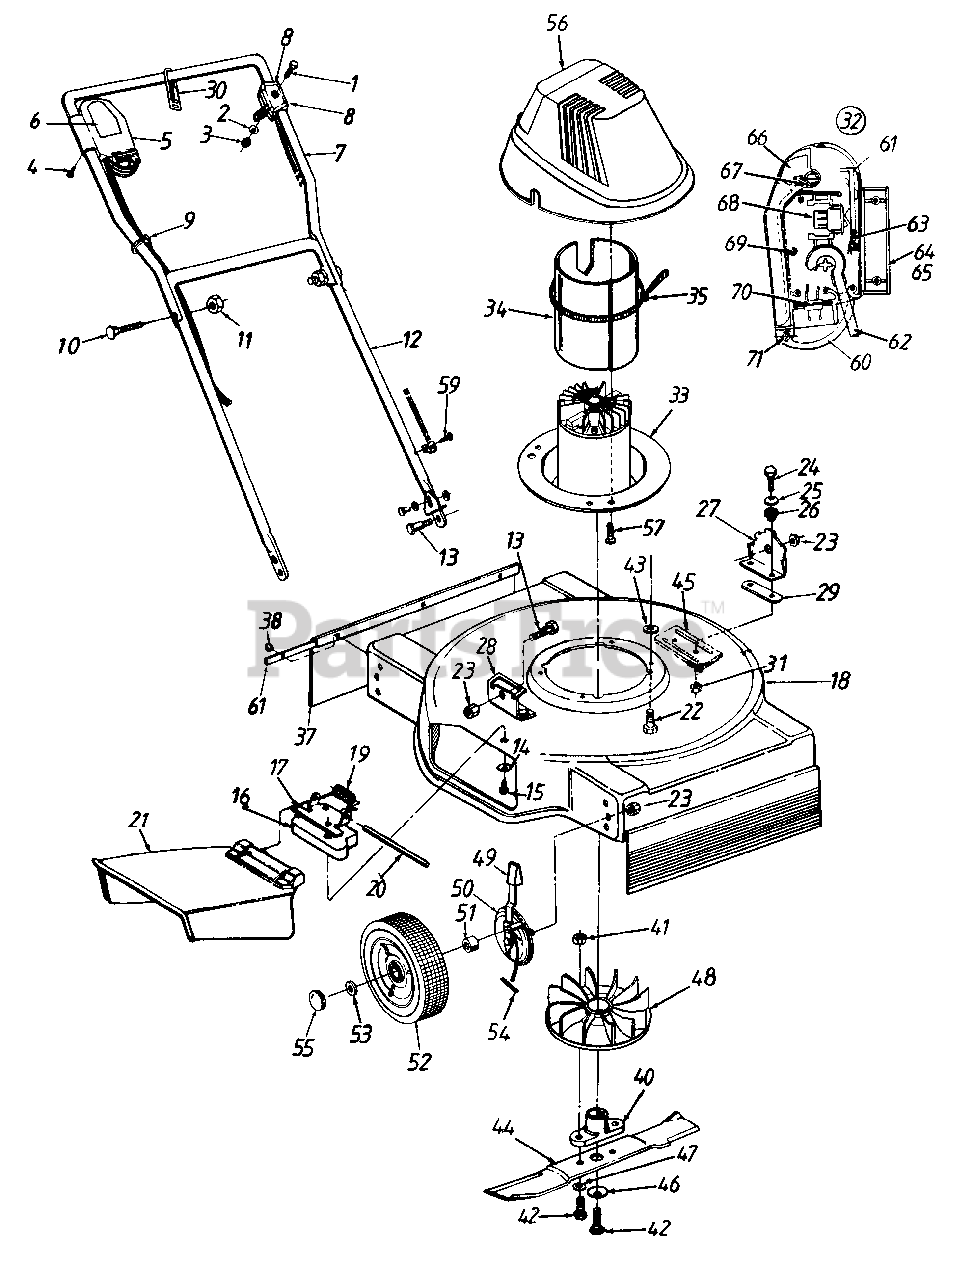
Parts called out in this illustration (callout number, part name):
1	Hex Bolt 1/4-20 x 1.5" Lg.
2	Fl-Wash .281" I.D. x .5" O.D.
3	Acorn Nut 1/4-20 Thd.
4	Self-Tap Scr. #7 x 1" Lg.
6	Label - Switch Box
7	Upper Handle
8	Control Flip Knob
9	Cable Tie
10	Curved Hd. Bolt 5/16-18 x 7/8" Lg.
11	Hex L-Nut 5/16-18 Thd.
12	Lower Handle
13	Shld. Bolt 3/8-16 Thd.
14	Bell-Wash. 1/4" I.D.
15	Self-Tap Scr. 1/4-20 x 1.12" Lg.
16	Spacer
17	Adapter Plate
20	Hinge Pin
21	Chute Deflector Ass'y.
22	Hex Self-Tap Scr. 3/8-16 x .75" Lg.
23	Hex Sems Nut 3/8-16 Thd.
24	Hex Bolt 1/4-20 x 1" Lg.
25	Fl-Wash..26" I.D. x .72" O.D.
26	Insulator Shield
27	Handle Brkt.- L.H.
28	Handle Brkt.- R.H.
29	Insulator Strap
30	Cord Restraint
31	Hex Nylon Lock Nut 1/4-20 Thd.
32	Cord & Switch Ass'y. Comp.
33	Motor & Switch Ass'y. Comp.
34	Insulator Motor Hsg.
35	Cable Tie
37	Flap - Rear & Front
38	Pop Rivet .188" Dia.
40	Blade Adapter
41	Hex Nut 3/8-24 Thd.
42	Hex Bolt 3/8-24 x 1.25" Lg.
43	Spacer
44	19" Blade
45	Deck Reinforcement Plate
46	Bell-Wash..4" I.D. x 1.14" O.O.
47	Bell-Wash. 3/8" I.D.
48	Motor Fan
50	Height Adj. Ass'y. (RF/LR)
51	Plastic Wheel Spacer
52	7" Wheel
53	Fl-Wash, .531" I.D. x .875" O.D.
54	Cotter Pin 3/32" Dia. x .75" Lg.
55	Hub Cap
56	Motor Cover
57	Screw #10 x .75" Lg.
59	Self-Tap AB-Tap Scr. #10-16 x .5" Lg.
60	Retainer Plug
61	Latch
62	Cord Ass'y.
63	Spring Latch
64	Housing - Upper Half
66	Handle - Switch Actuator
67	Spring - Switch Handle
68	Switch
69	Screw #6-32 x .5" Lg.
70	Plug Ass'y.
71	Retainer Plug Spring
